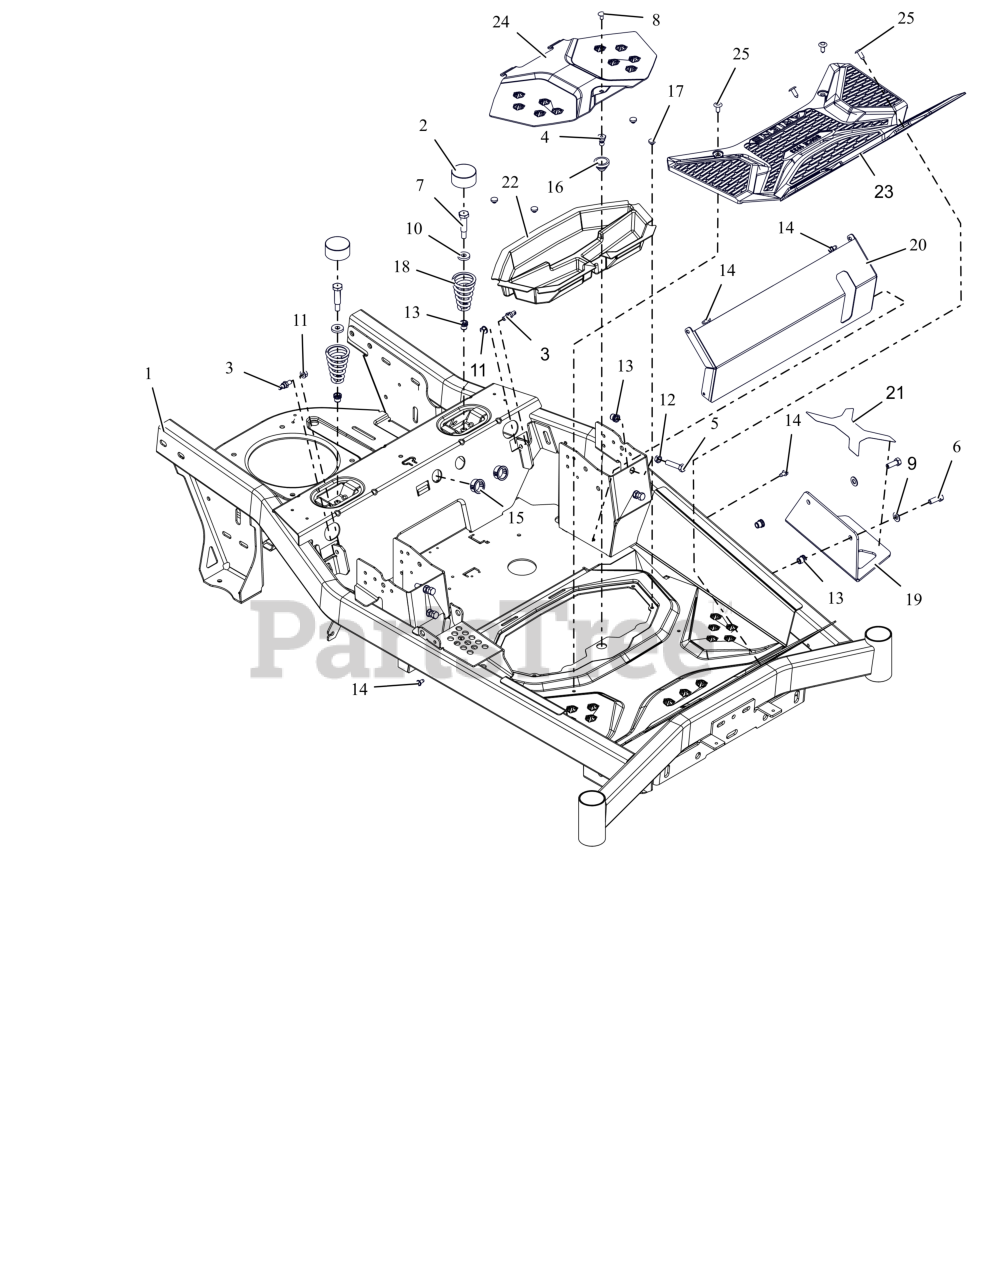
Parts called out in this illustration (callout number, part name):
1	KIT,ARIENS FRAME W/ DECALS
2	HUB CAP
3	COUPLER, DAMPER MOUNT
4	STUD, BALL FEMALE .250-20 THREAD
5	BLT, HEX .38-16X1.75F G5 ZCC
6	BLT, HEX .38-16X1.00 G8ZCCEP30
7	BLT-SHLDR .50X1.50 .375-16 ZCC
8	BLT, RHSSN.25-20X.500 G5 ZCC
9	WSHR,FLT .406X.812X.065 ZCC
10	WSHR, FLT .406X1.00X.188 ZCC
11	NUT-LK-TOP-FLG .312-18 GF ZCC
12	NUT-JAM .375-16 G2 ZCC
13	NUT,THD,INSERT .38-16 ZC120
14	SCR-TAP .25-20X.50 HWH ZCC
15	BSHG, PANEL SNAP .937X1.11X.56
16	COUPLING, RUBBER PUSH-IN
17	BUMPER GROMMET
18	SPRING, SEAT
20	PLATE- FRONT KICK
21	GRIP- TAPE - STEP -ARIENS
22	INSERT, GRAVELY STORAGE
23	MAT- RUBBER FOOTBOARD- IKON
24	KIT, ARIENS ACCESS PLT W/DECAL
25	XMAS TREE FASTNER-BLACK
